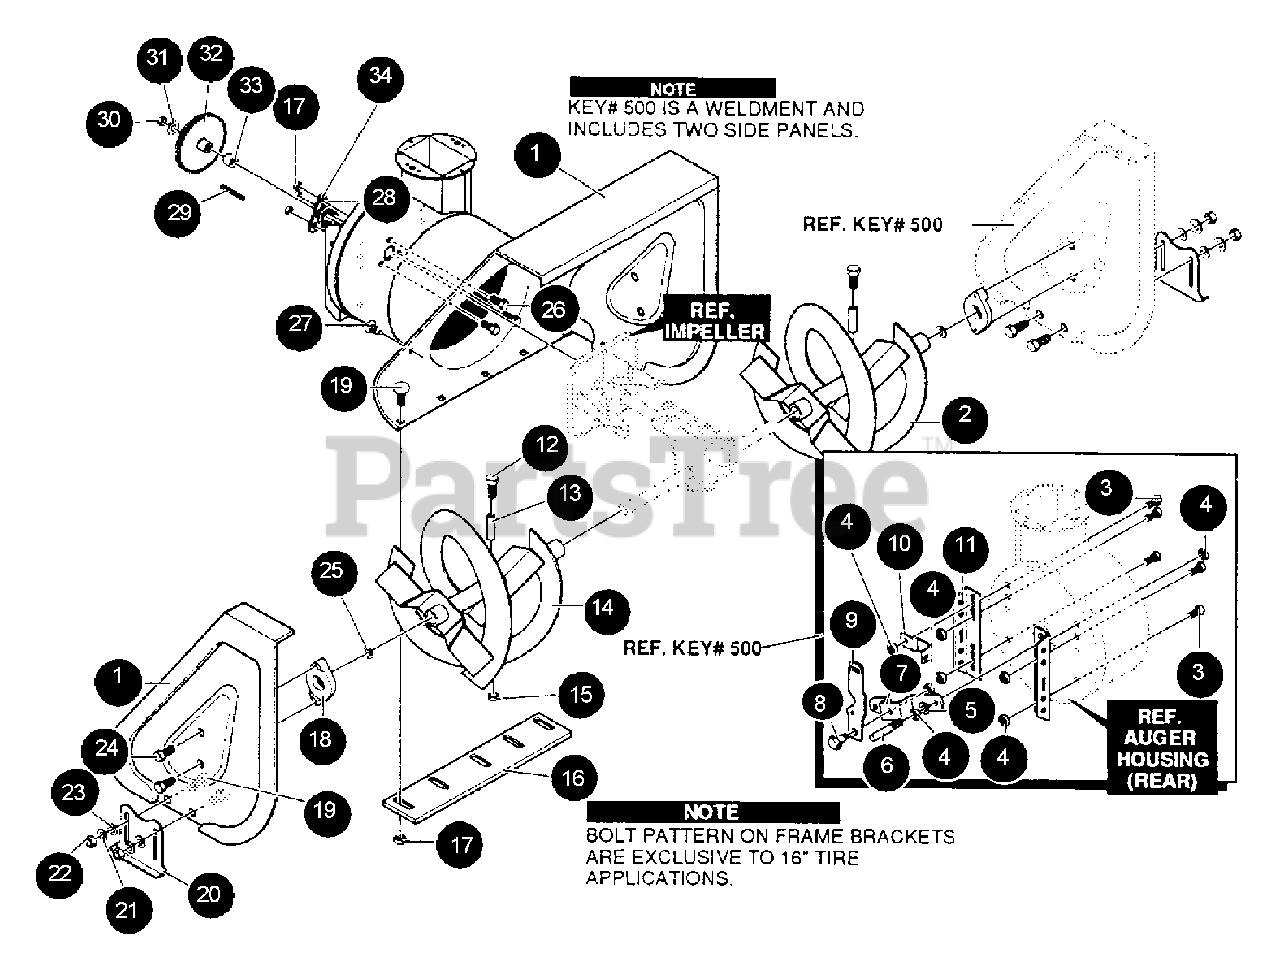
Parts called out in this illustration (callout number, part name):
1	AUGER INTAKE ASSY
2	AUGER ASSY - RIGHT
3	SCREW - 3/8-16×0.75" -- HEX HEAD CAP
4	NUT, 3/8"-16
5	WASHER. REGSPTLK 0.393×0.68×0.10
6	STUD, BRAKE ARM
7	PLATE, CLUTCH
8	BOLT - 3/8-16
9	BRACKET, IDLER
10	BRACKET, CABLE
11	BRACKET, MOUNTING
12	SCREW 1/4"-20
13	SPACER
14	AUGER ASSY - RIGHT
15	NUT, 1/4"-20
16	BLADE, SCRAPER
17	NUT, 5/16"-18
18	BEARING, AUGER SHAFT
19	BOLT, CARRIAGE 5/16-18×0.75
20	SKID, HEIGHT ADJUST
21	WASHER
23	WASHER
24	SCREW, 5/16-18×0.75 WAHHTAP
25	WASHER, FLAT
26	SCREW 5/16"-18×0.75
27	PLUG, CHRISTMAS TREE
28	BEARING, BALL
29	KEY, SQUARE 0.18SQX88LG
30	LOCKNUT - 1/2-20
31	WASHER, FLAT
32	PULLEY, V4L
33	SPACER
34	RETAINER, BEARING
